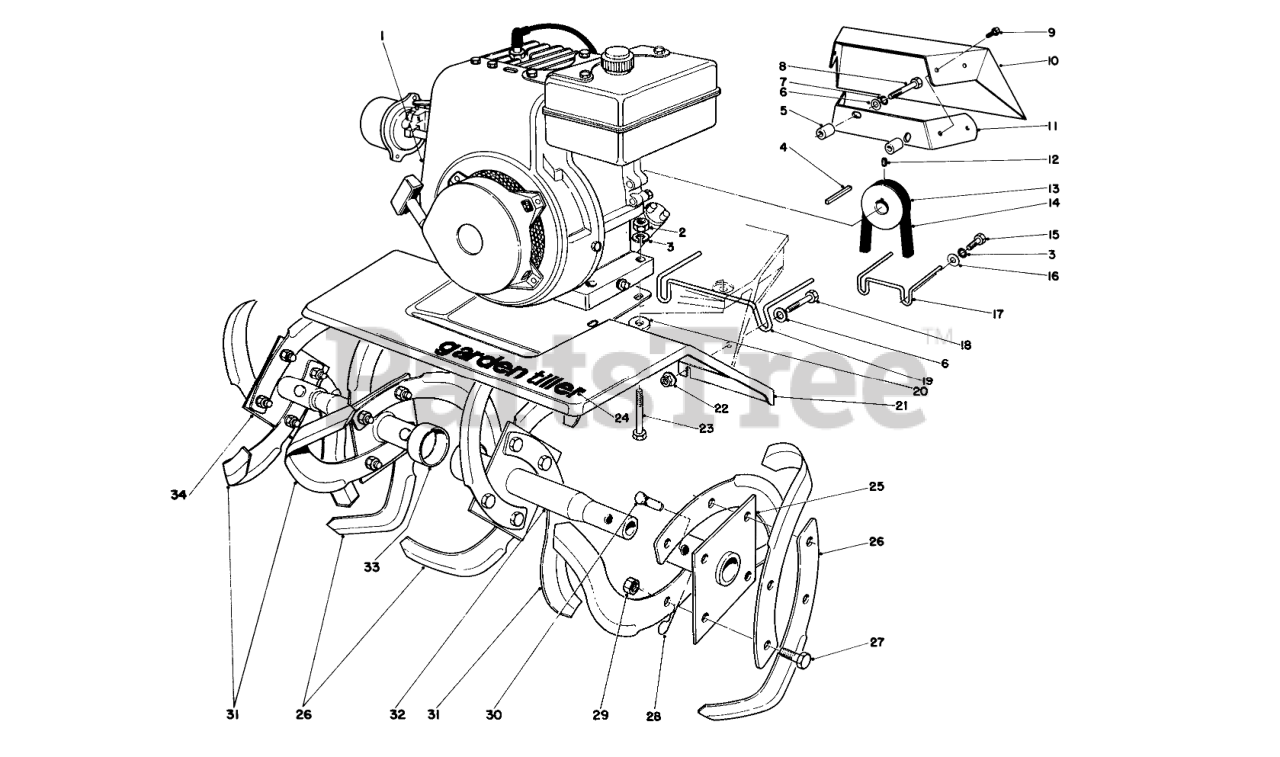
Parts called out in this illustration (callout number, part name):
1	Engine
2	NUT-HEX
3	WASHER-LOCK
4	KEY-SQUARE
5	Spacer
6	WASHER-FLAT
7	WASHER-LOCK
8	SCREW-HH
9	SCREW-HWHTF
10	PULLEY GUARD
11	Strap-Belt Shield
12	SCREW-HSH
13	Engine Pulley
14	V-BELT
15	SCREW-HH
16	WASHER-PLAIN
17	Belt Guide
18	SCREW-HH
19	BELT GUIDE
20	WASHER-FLAT
21	TINE SHROUD
22	NUT-LOCK, HHF
23	SCREW-HH
24	Decal
25	Axle L.H.Outer
26	RH TINE
27	SCREW-HH
28	PIN-COTTER
29	NUT-KEPS
30	TINE PIN
31	LH TINE
32	Axle L.H. Inner
33	Axle R.H. Inner
34	Axle R.H. Outer
